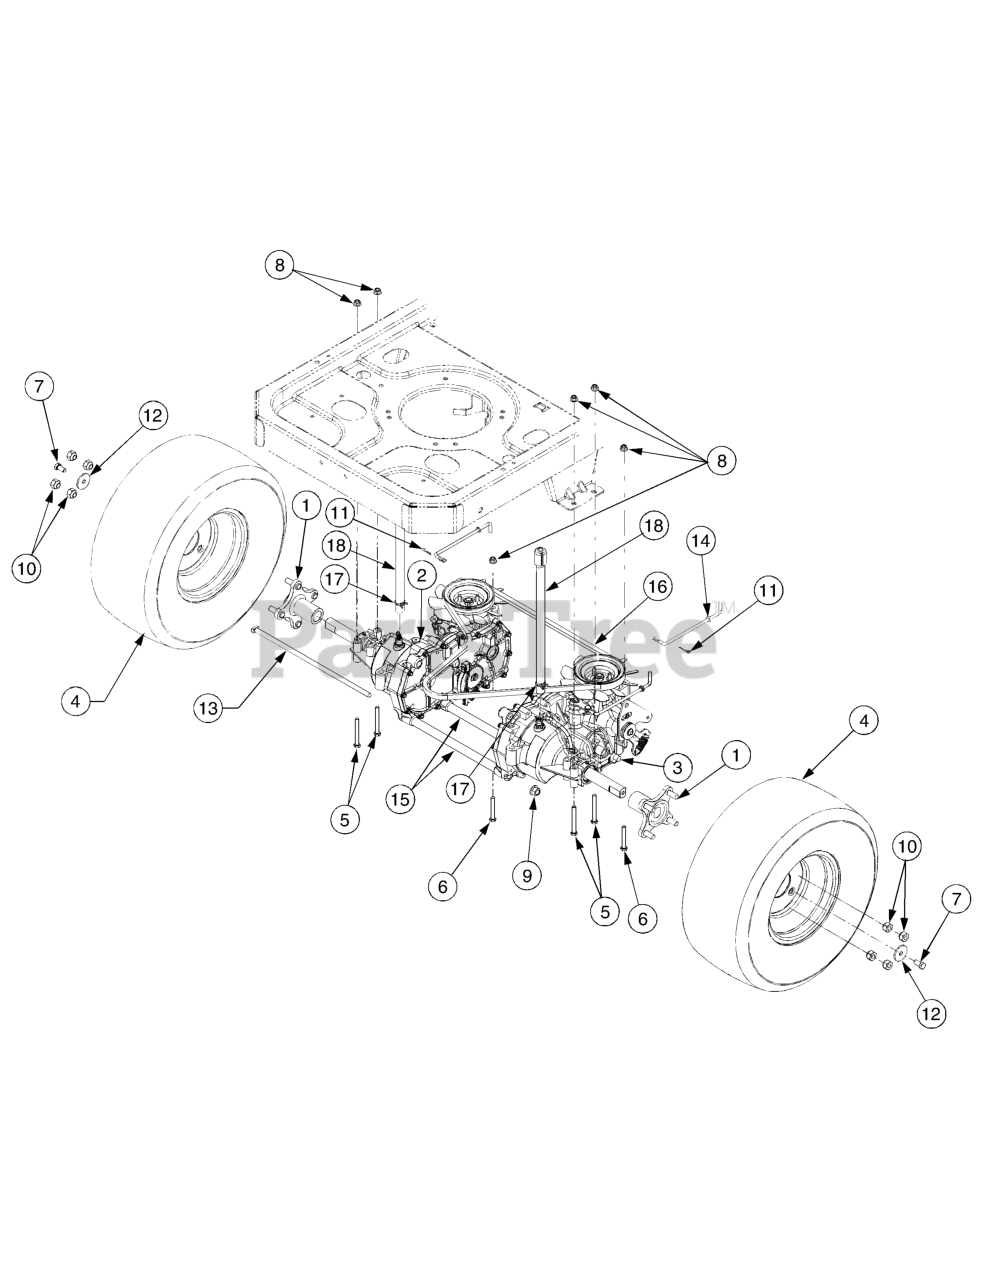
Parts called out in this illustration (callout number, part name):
1	Hub, Wheel
1	Stud, Rib Neck, 7/16-14 x 1.6
2	Transmission Assembly, LH
3	Transmission Assembly, RH
4	Valve Assembly
5	Screw, Hex Cap, 5/16-18 x 2.75 GR5
6	Screw, Hex Cap, 5/16-18 x 2.25 GR5
7	Screw, Hex Cap Lock, 3/8-16 x .75 GR5
8	Nut, Hx Flnge Insert Lck, 5/16-18 GrF
9	Nut, Hex Flange Lock, 7/16-20 GrB
10	Nut, Lug, 7/16-14
11	Pin, Cotter, 3/32 x .75
12	Washer, Flat, .39 x 1.5 .134
13	Rod, .405 x 14.0
15	Tube, .45 x .69 x 10.2
16	V-Belt, Type A Sec x 57.7
17	Clamp, Hose
18	Hose, Breather
